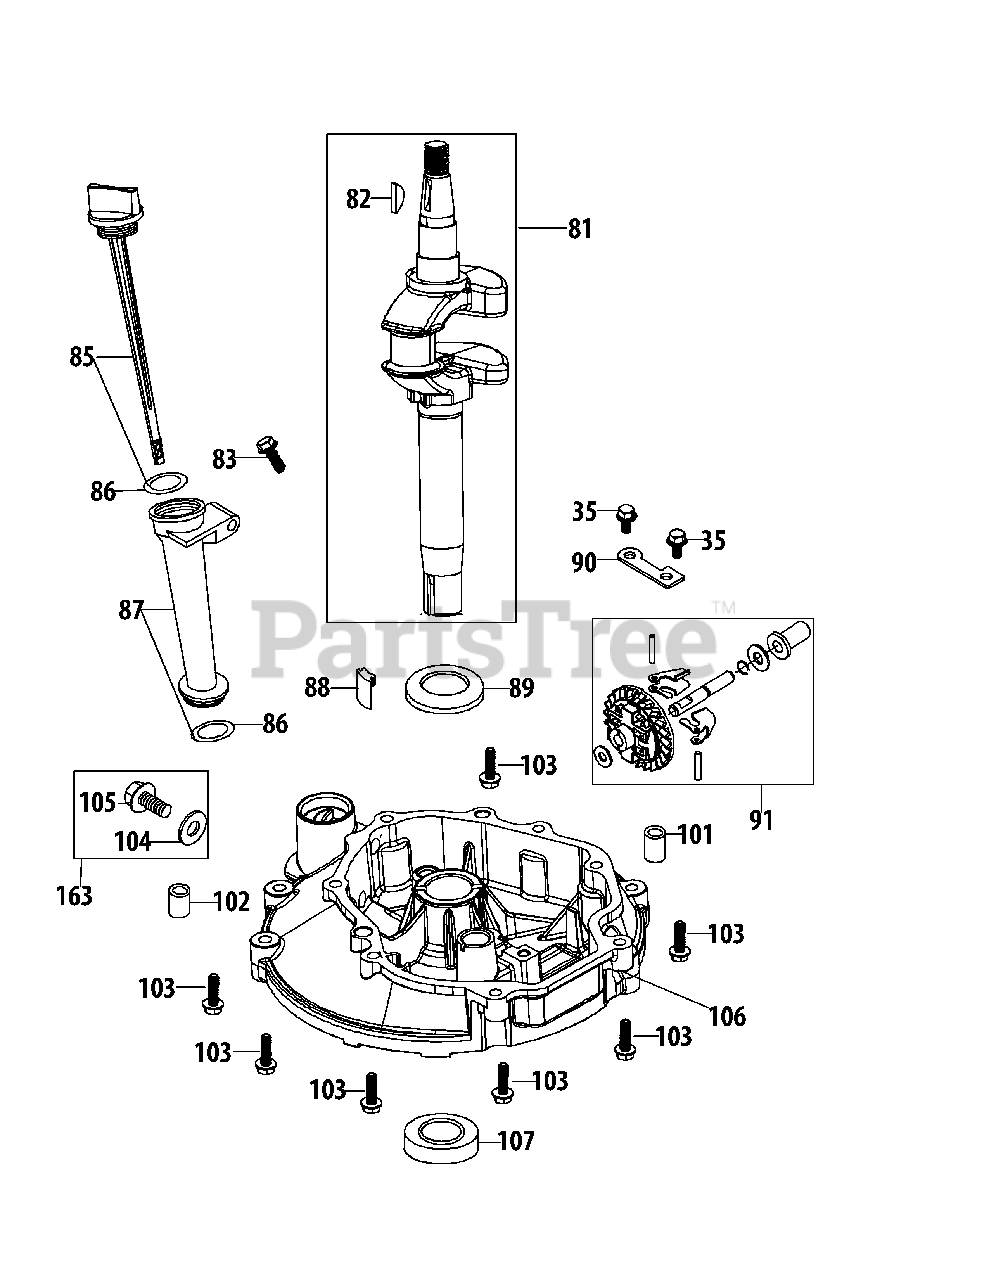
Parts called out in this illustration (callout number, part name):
35	Bolt M6X14 Multi-Purpose
81	Crankshaft Assembly
82	Flywheel Key
83	Bolt M6X35 Af Base/Brake/Dipstick
85	Oil Dipstick Assembly
86	Dipstick / Oil Fill Tube O-Ring
87	Oil Fill Tube Assembly
88	Oil Return Seal
89	Crankshaft Thrust Washer
90	Governor Gear Mounting Plate
91	Governor Gear/Shaft Assembly
101	Crankcase Cover Dowel Pin
102	Crankcase Cover Dowel Pin
103	Bolt M6X28 X65/P65 Crankcase
104	Oil Drain Plug Washer
105	Oil Drain Plug
106	Crankcase Cover
107	Lower Crankshaft Seal
163	Oil Drain Plug & Washer Ass'Y
